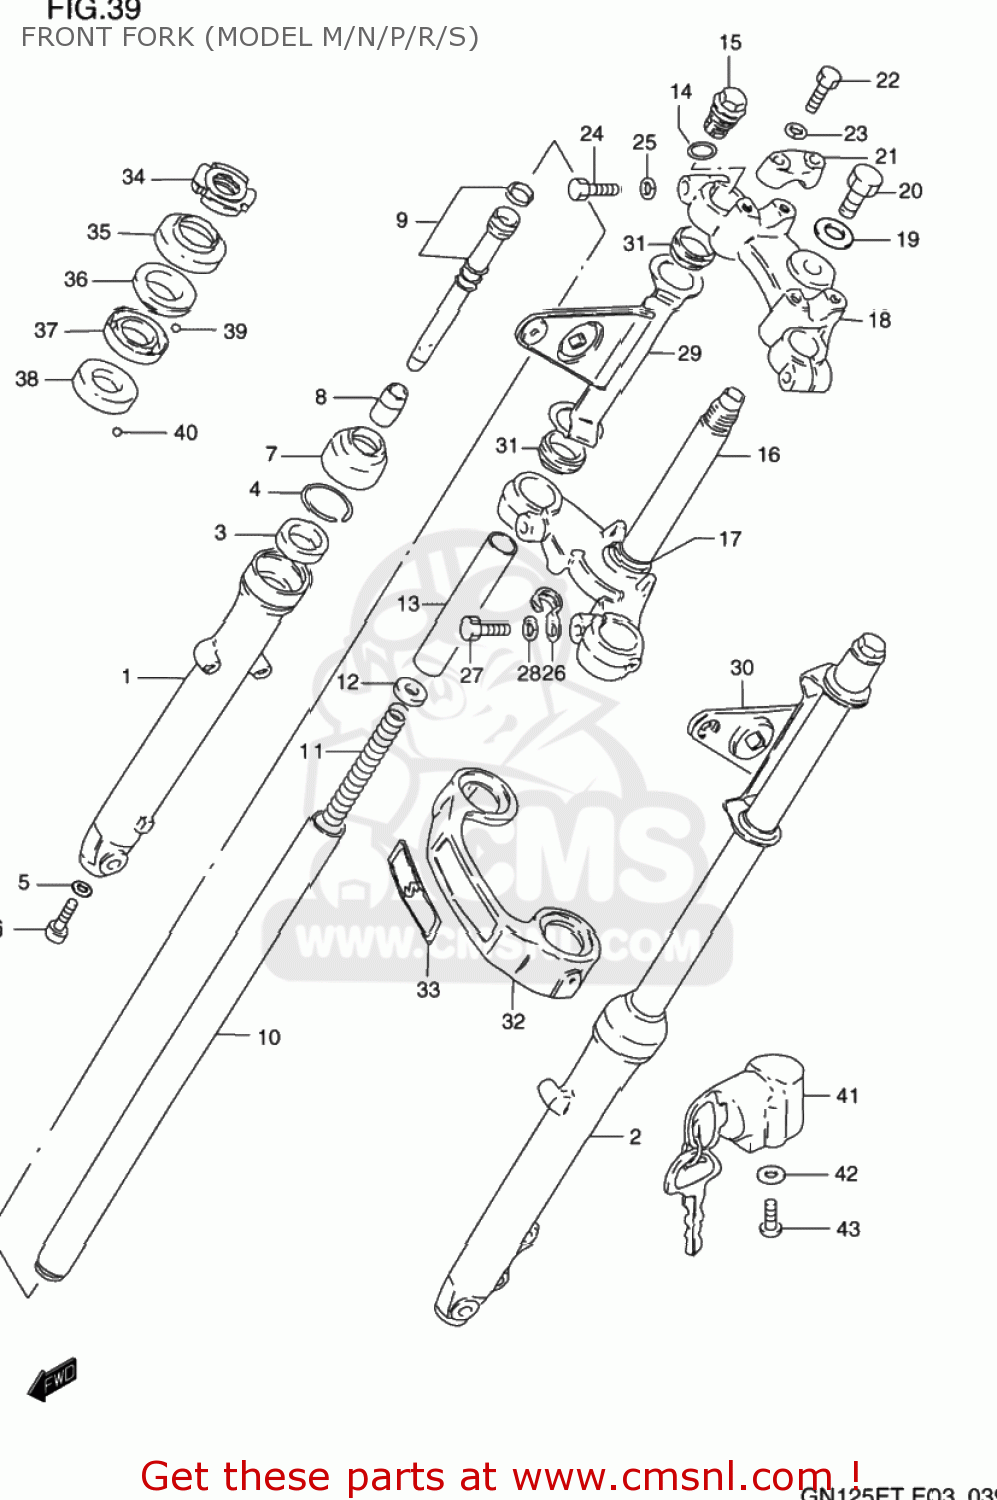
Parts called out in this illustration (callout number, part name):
1	TUBE,OUTER,R
2	TUBE,OUTER,L
3	SEAL,OIL
4	RING,SNAP
5	GASKET (NAS)
6	BOLT,FORK CYLINDER(10X25)
7	SEAL,DUST
8	PIECE,OIL LOCK
9	CYLINDER
10	TUBE,INNER
11	SPRING
12	GUIDE,SPRING COVER
13	SPACER
14	O RING
15	CAP
16	STEM,STEERING
17	RACE,STEERING OUTER LWR
18	HEAD,STEERING STEM(BLACK)
19	WASHER,STEM HEAD(10.5X30X3.2)
20	BOLT,FORK INNER TUBE
21	HOLDER,HANDLE(BLACK)
22	BOLT
23	LOCK WASHER
24	BOLT,FORK INNER TUBE F
25	WASHER,LOCK
26	CLIP
27	BOLT,FR FORK LWR(12X33)
28	WASHER,LOCK
29	BRACKET,HEADLAMP,R
30	BRACKET,HEADLAMP,L
31	CUSHION,HEADLAMP BRACKET
32	COVER,FR FORK
33	EMBLEM,FR FORK COVER
34	NUT,STEERING STEM(25X44X10)
35	DUST SEAL,STEERING UPR
36	RACE,STEERING OUTER UPR
37	RACE,STEERING INNER UPR
38	LACE,STEERING INNER LWR
39	BALL
40	BALL
41	LOCK ASSY,STEERING
42	LOCK WASHER
43	SCREW
